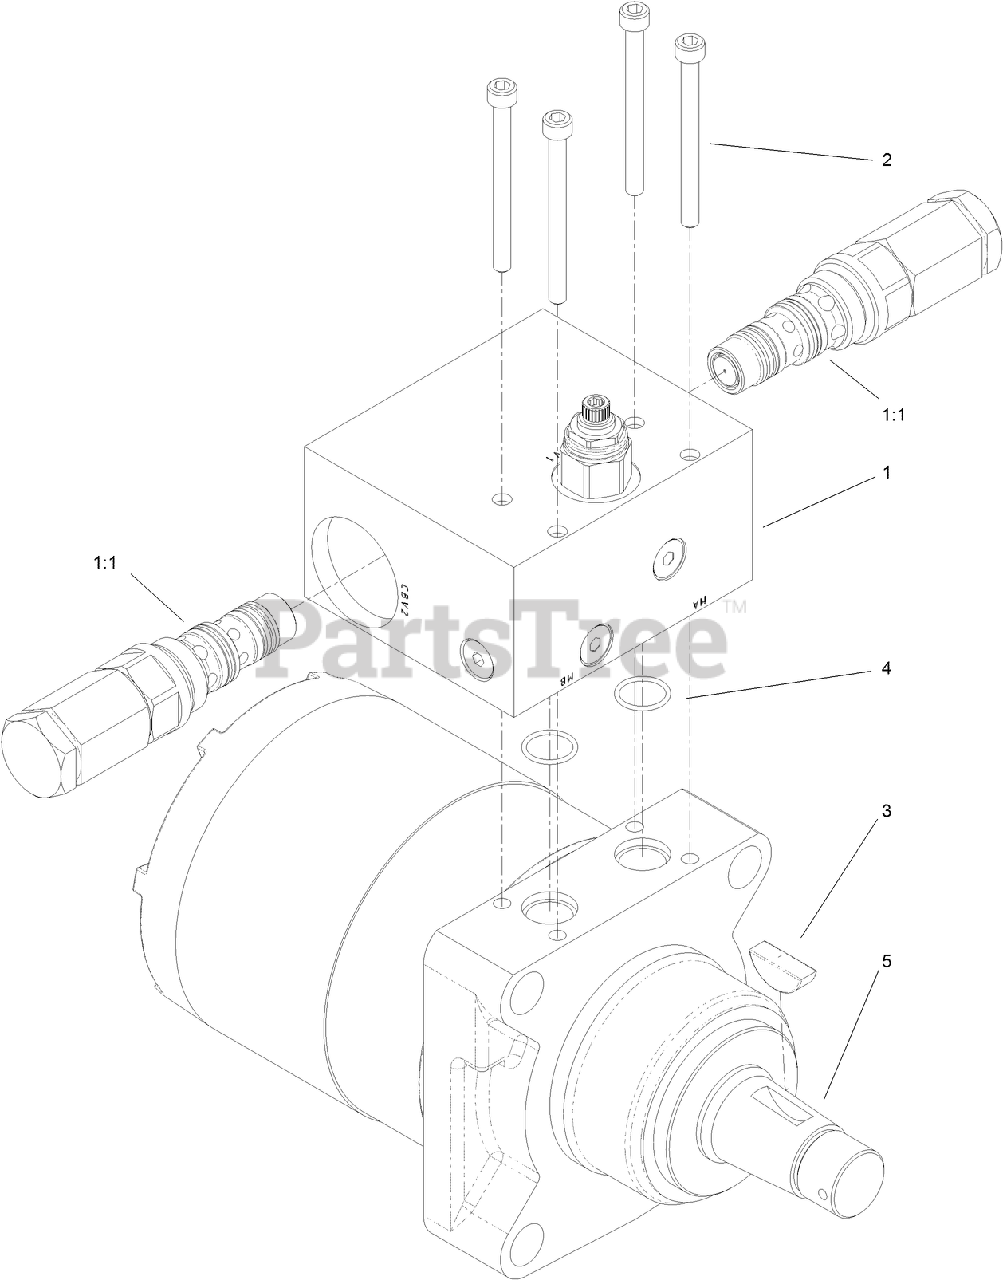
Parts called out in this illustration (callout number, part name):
1	COUNTERBALANCE VALVE ASM
1:1	CARTRIDGE-CB
2	BOLT-HSH
3	KEY-WOODRUFF
4	O-RING
5	SHAFT-COUPLING
